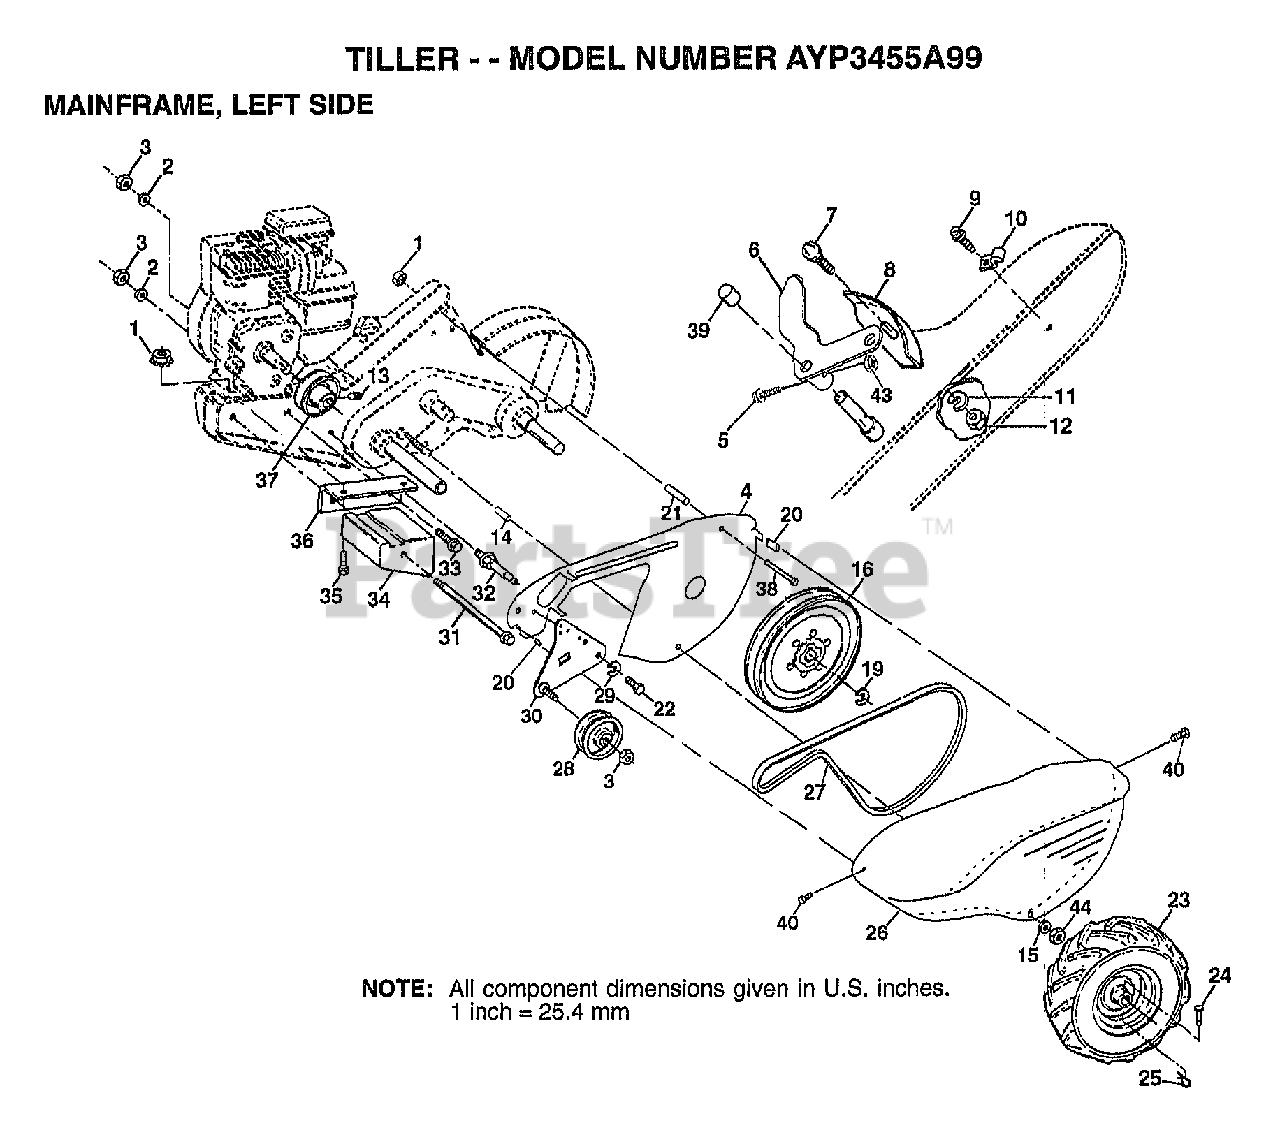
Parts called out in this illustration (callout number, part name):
2	LOCKWASHER
3	NUT.HEX.3/8-16UNC
4	SHIELD.INNER.BELT
5	"SCREW-LEVER,SHI"
6	LEVER ASM CRT
7	BOLT
8	PANEL TI
10	CONDIUT CLIP T
11	LOCKWASHER
13	SET SCREW
14	SPACER-SPLIT
15	WASHER
16	SHEAVE.TRANS.
20	NUT J CLIP #8
21	SPACER CRT
22	BOLT.FIN.HX.5/16-24X1/2
23	TIRE TI
23	RIM
24	RIVET.DRILL.1.75
25	RETAINER M
26	GUARD.BELT
27	BELT-V
28	PULLEY-IDLER TI
29	KLIP RING
30	BRACKET ASM IDLER
31	BOLT CRT
32	SHIFT ARM CRT
33	BOLT
34	COUNTERWEIGHT CRT
35	BOLT.HEX.5/16-1.5
36	BRACKET LH CRT
37	ENGINE PULLEY
39	CAP PLUNGER BLACK
40	SCREW HX WSH.HD#8-18X1/2
43	LOCKNUT
44	NUT
